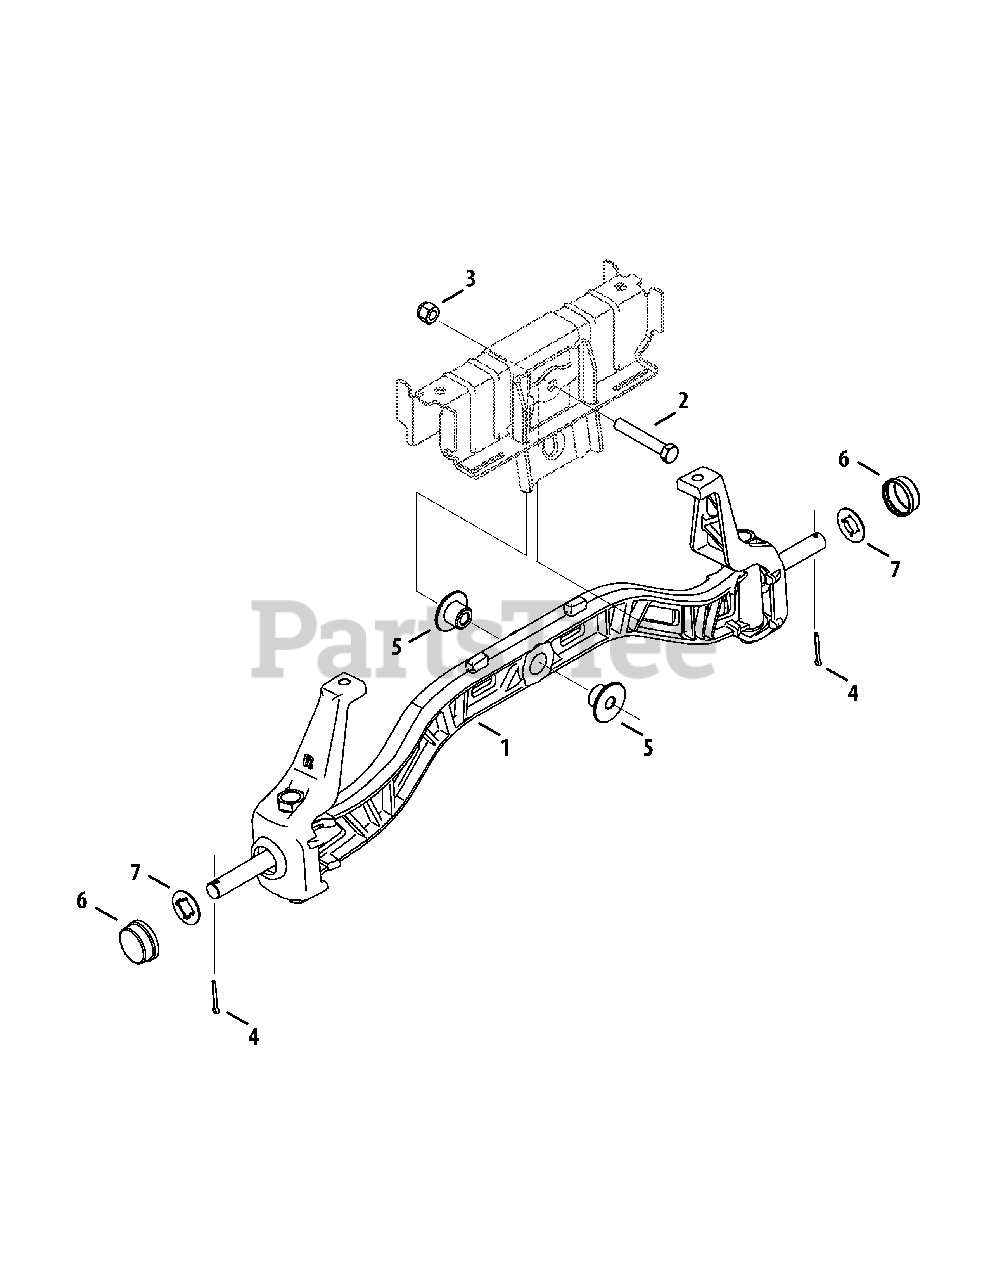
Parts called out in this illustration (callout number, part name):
1	Axle Assy, LH
1	Axle Assy, RH
1	Axle, Cast Pivot Bar
1	Bolt, Shoulder .75 x 4.20 x 1/2-13
1	Bearing, Flange .75 x 1.00 x 1.12
2	Hex Cap Screw, 1/2-13 x 3.00
3	Nut, Hex Lock, 1/2-13
4	Pin, Cotter, 5/32, 1.25
5	Shoulder Spacer, 1.00 x .515 x .760
6	Hub Cap
7	Washer, Flat, .350 x 1.559 x .062
